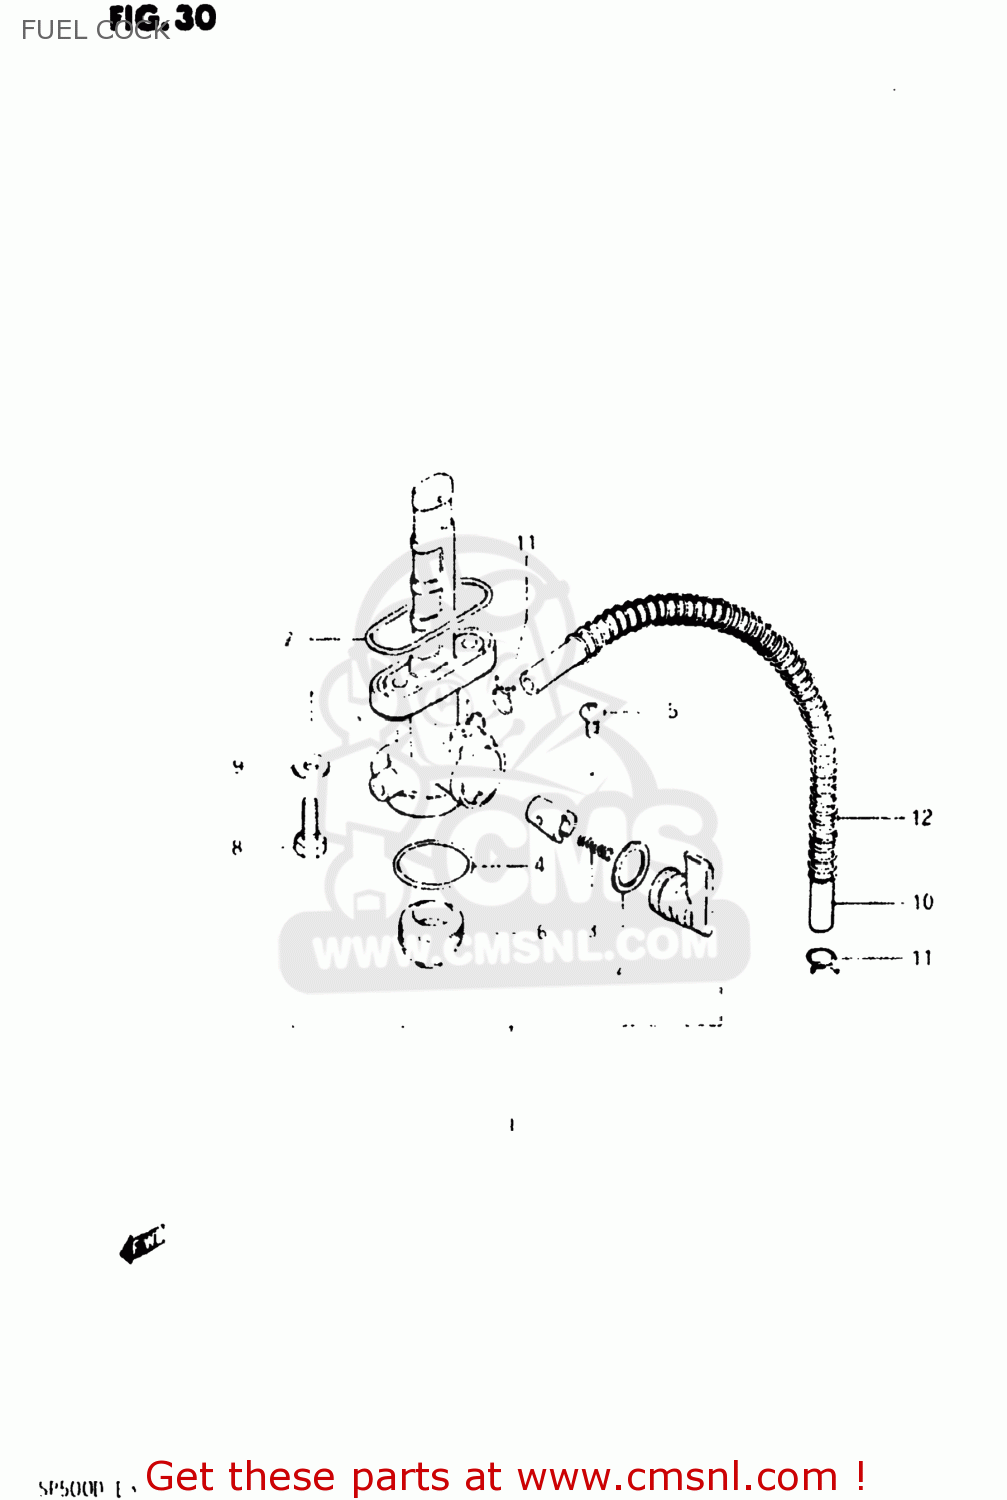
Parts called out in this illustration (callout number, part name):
1	COCK ASSEMBLY,FUEL
2	O-RING
3	SPRING
4	GASKET,FILTER (NAS)
5	SCREW,FUEL COCK LEVER
6	CUP,STRAINER
7	O RING,FUEL COCK
8	BOLT(6X20)
9	GASKET
10	HOSE
11	CLIP
12	SPRING
